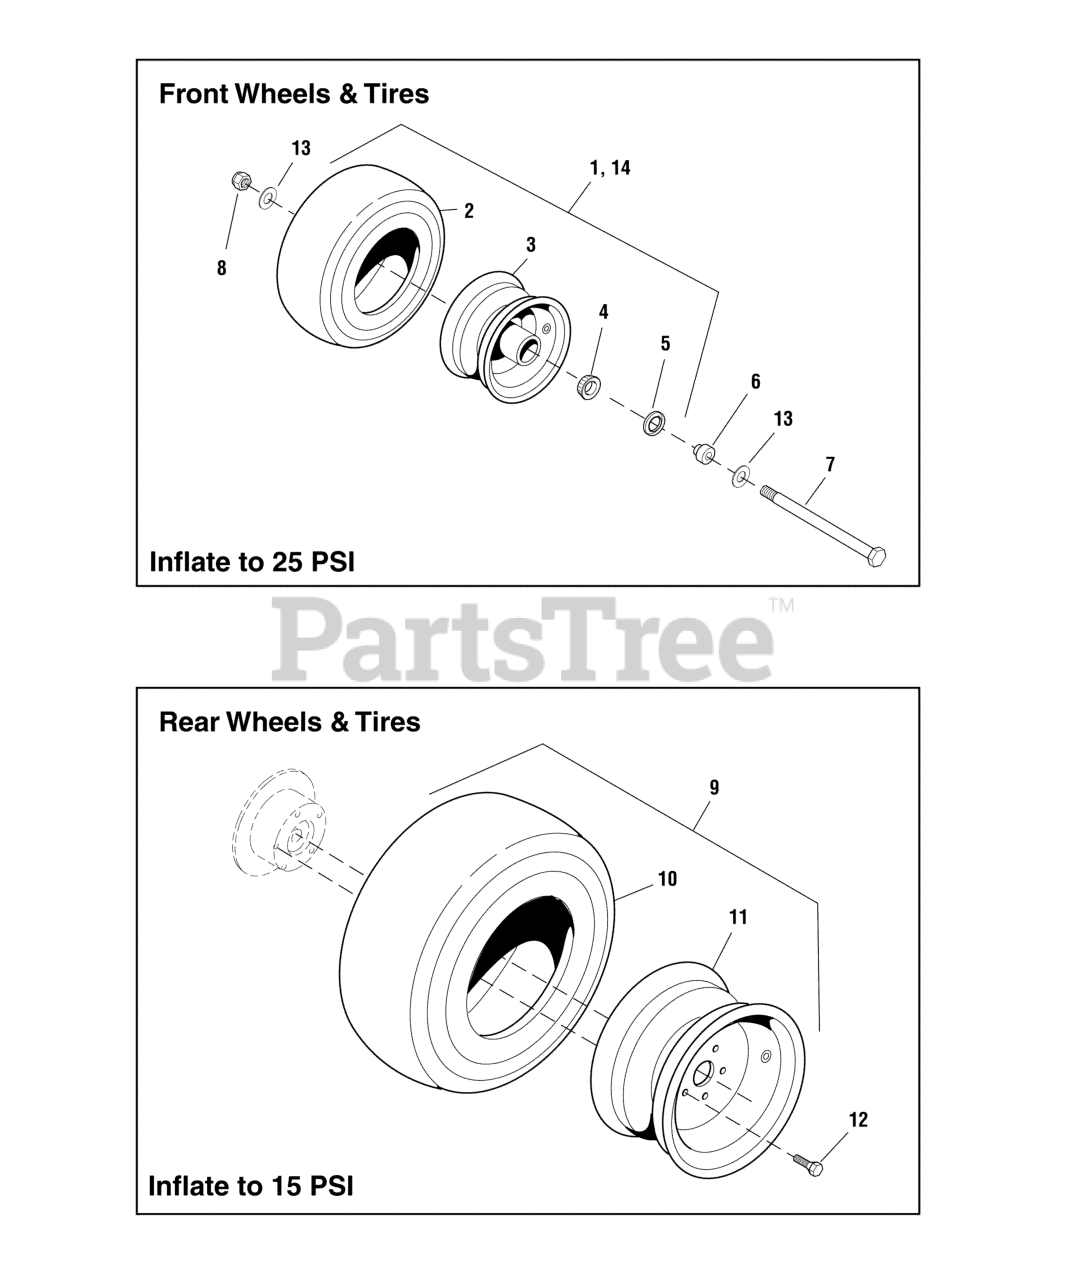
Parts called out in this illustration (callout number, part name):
1	TIRE ASSM, 13 X 6.5 - 6, PNE / TB
2	TIRE, RUBBER ONLY
3	WHEEL ASSEMBLY, For 13 x 6.5 x 6 Tires, Complete (SV)
4	BEARING, Tapered Roller
5	SEAL, GREASE
6	ADAPTER, CASTER AXLE, CZ
7	BOLT, 1/2-13 X 9" GD5 YZ
8	NUT, Hex Flange, Nylock, 1/2-13
9	TIRE WHEEL ASM, 24X12.00-12, TURF MASTER
10	TIRE, 24 X 12 X 12
11	WHEEL, 12 X 8.5
12	BOLT, WHEEL LUG, 1/2 X 1-5/8
13	WASHER, 1/2 SAE
14	TIRE ASSM, 13 X 6.5 - 6, FF / TB
